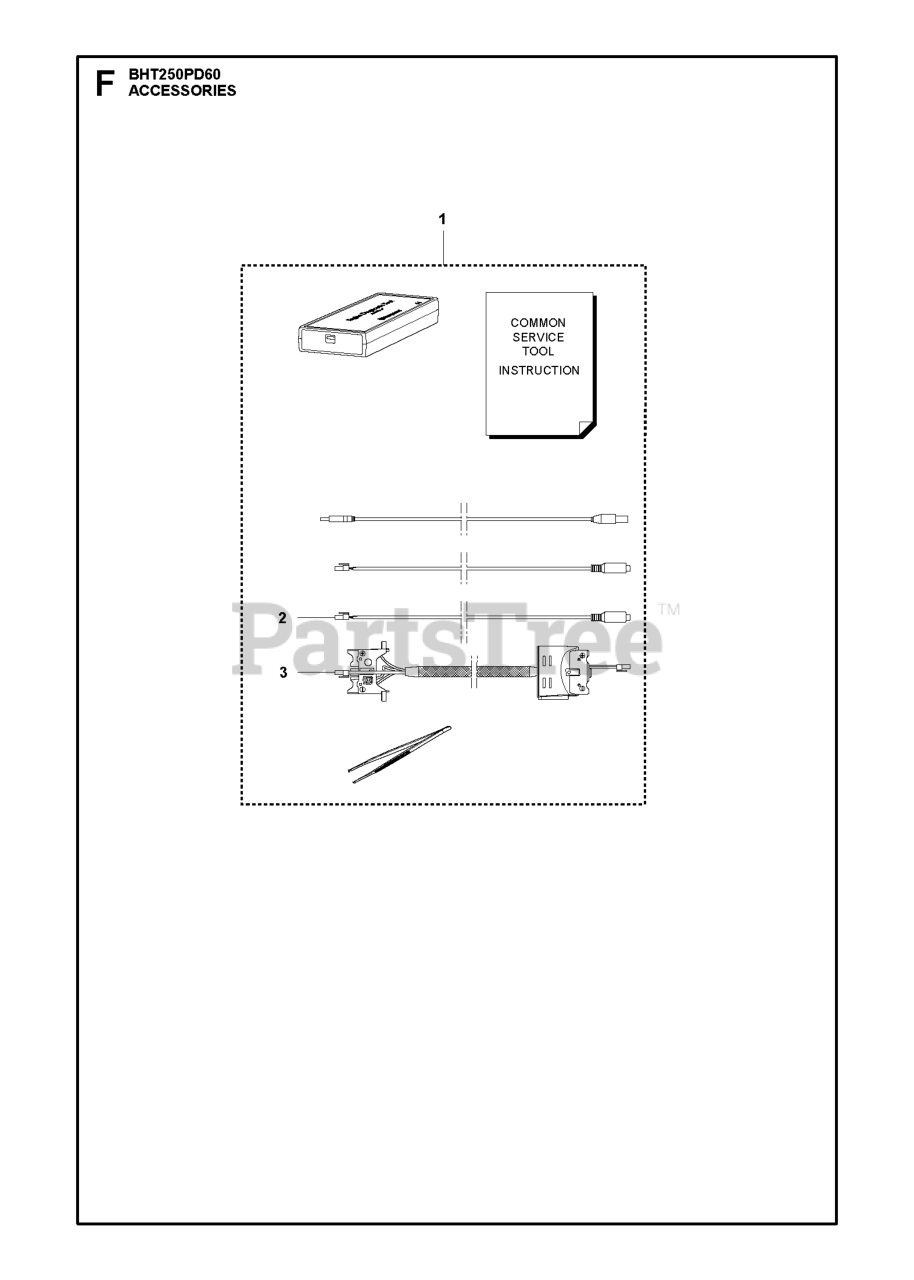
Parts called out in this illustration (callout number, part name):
1	DIAGNOSTIC TOOL KIT
2	WIRING ASSY
3	CABLE ASSY
